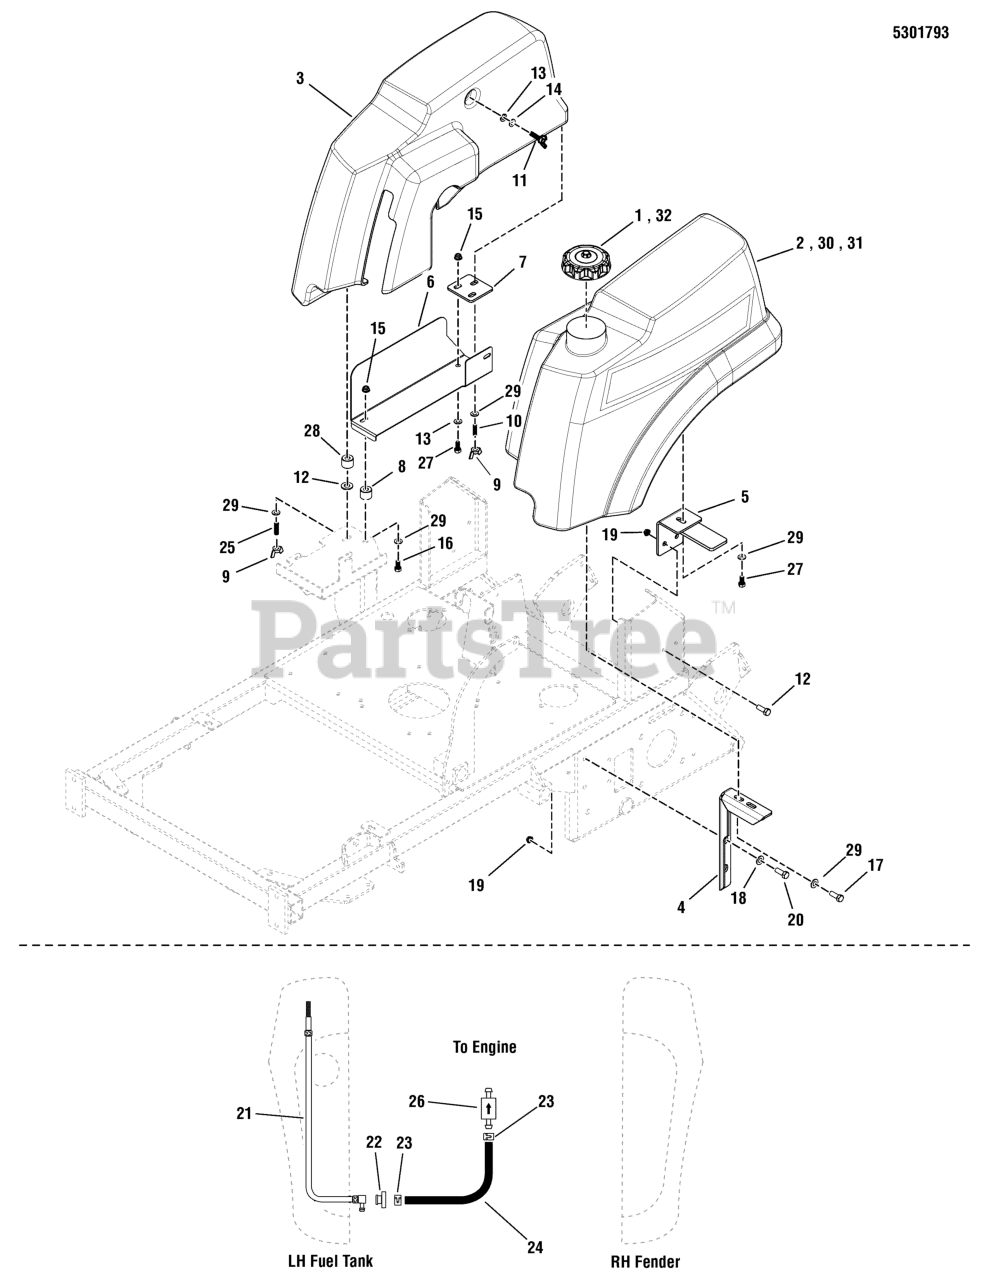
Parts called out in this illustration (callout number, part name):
1	CAP, GASOLINE, VENTED
2	FUEL TANK, S75X, SNP PRO 48/52
3	FENDER, S75X, SNP PRO, 48/52
4	WELD, MOUNT, FUEL TANK, FRONT - RED
5	WELD, REAR TANK MOUNT, LH - RED
6	GUARD, OIL FILTER - RESERVOIR, S75X - RED
7	PLATE, RIGHT REAR TANK MOUNT - RED
8	SPACER, .38 X .75 X 1.25, YZ
9	NUT, 5/16-18 WING NYLON LOCK
10	SOC SET SCREW, 5/16-18 X 1-1/2 SS
11	WING, SCREW, 5/16-18 X 1-1/4, CZ
12	5/16 PUSH-ON NUT RETAINER, STL, CZ
13	WASHER, 5/16" SAE
14	WASHER, 5/16 LOCK CZ
15	NUT, 5/16-18 HEX NYLOCK FLANGE
16	BOLT, 5/16-18 X 2 GD5 YZ
17	BOLT, 5/16-18 X 3/4 GD5
18	WASHER, 3/8 SAE
19	NUT, 3/8-16 HEX NYLOCK FLANGE
20	BOLT, 3/8-16 X 1" GD5 CZ
21	PICKUP TUBE ASM, FUEL TANK, 18.38" (SV)
22	BUSHING-FUEL TANK RED RUBBER
23	CLAMP, HOSE, EXTERNAL, 1/2 - RED
24	HOSE, 1/4" FUEL, 24.00"
25	SCREW, SOC SET, 5/16-18 X 2-1/2, SS
26	FUEL FILTER (SV)
27	BOLT, 5/16-18 X 1 GD5
28	SPACER, .39 X .75 X 1.06
29	WASHER, 5/16 GD.9 FLAT
30	TANK, FUEL, SNP PRO, EVOLUTION 48/52
31	TANK, FUEL, SNP PRO EVOLUTION, 48/52
32	FUEL CAP, 3-1/2", MANAGED VENT OUT, 12"
